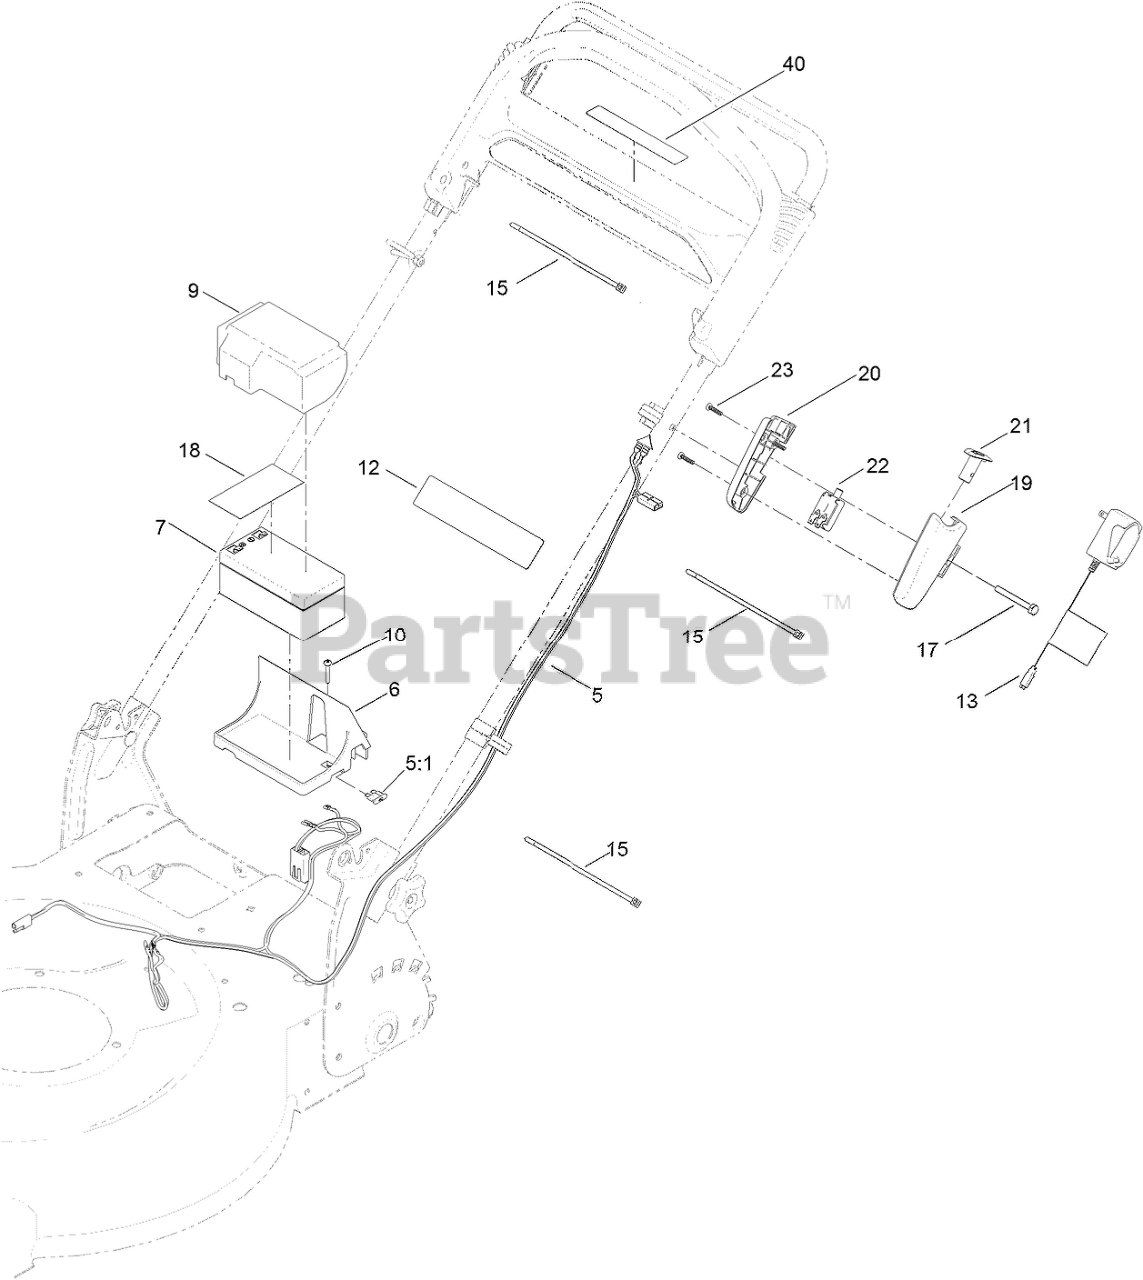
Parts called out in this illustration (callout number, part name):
5	HARNESS-WIRE
5:1	FUSE-40 AMP
6	TRAY-BATTERY
7	BATTERY-WET
9	COVER-BATTERY
10	SCREW-PPH, PLASTITE
12	DECAL-WARNING
13	CHARGER-BATTERY
15	TIE-CABLE
17	SCREW-HH
18	DECAL-TERMINAL, BATTERY
19	HOUSING-SWITCH, LH
20	HOUSING-SWITCH, RH
21	BUTTON-SWITCH
22	SWITCH-PUSH BUTTON
23	SCREW-PPH
40	DECAL-BUTTON, PUSH
